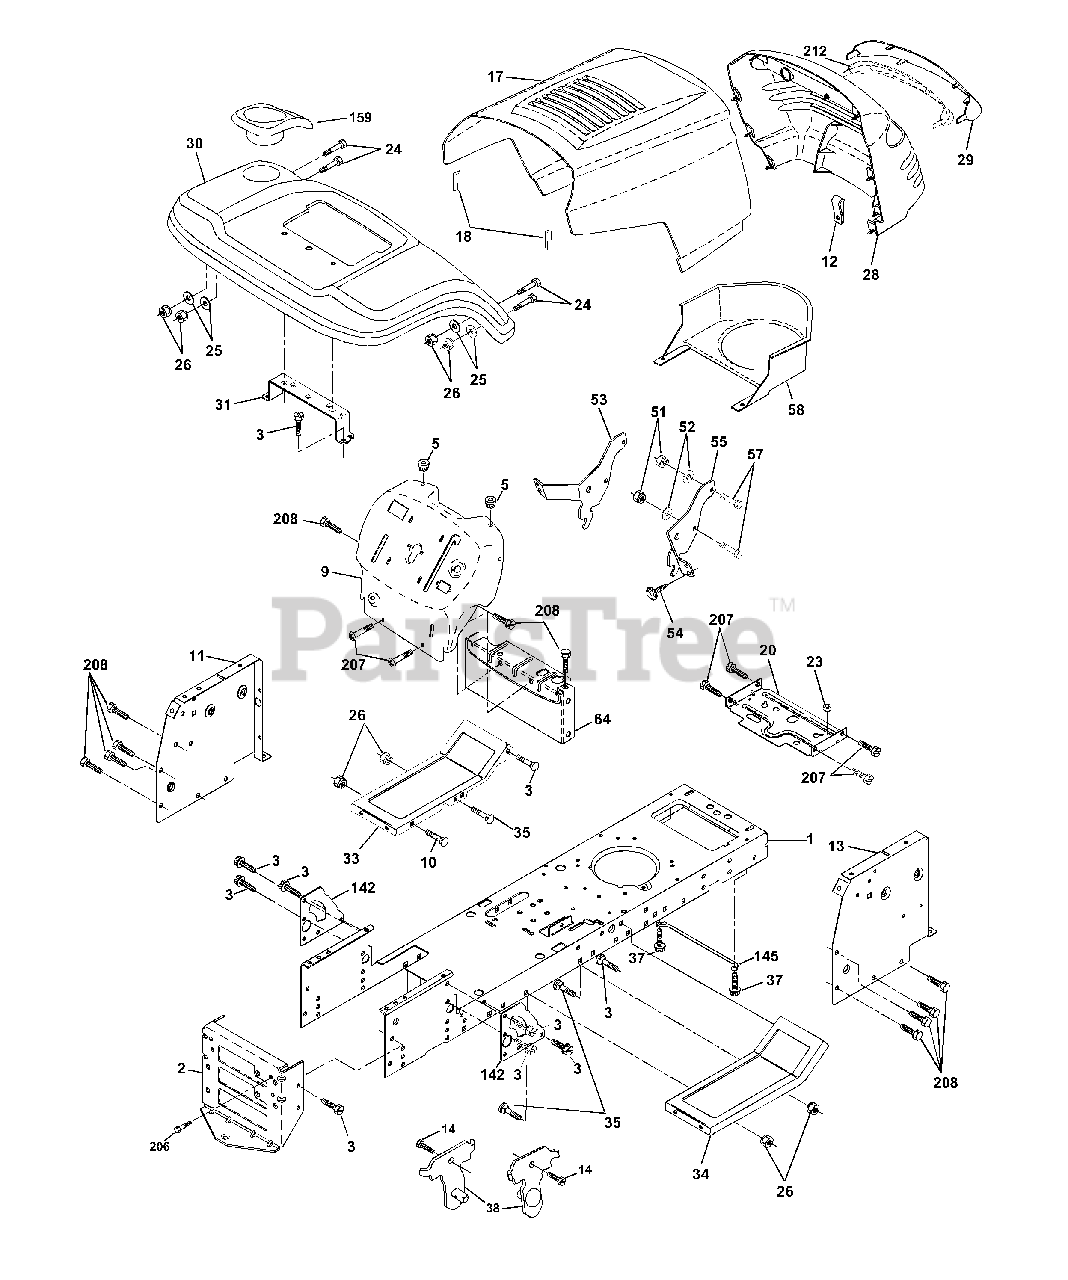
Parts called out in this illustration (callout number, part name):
1	Chassis
2	Drawbar
3	Screw 3/8-16 X .75
5	Bumper Hood/Dash
9	Dash P/L
10	Bolt Carriage 3/8-16 x 1
11	Panel Dash Lh
12	Clip Tinnerman
13	Panel Dash Rh
14	Screw Thdrol 3/8-16 x1/2
17	Hood LT/PL
18	Bumper Hood
20	Plate Mtg Battery Fuel Tank Fr
23	Bushing
24	Bolt Fin Hex 3/8-16 x 1 Gr 5
25	Washer 13/32 X 13/16 X 12 Ga
26	Nut Lock Hex W/Ins 3/8-16 Unc
28	Grille/Lens Asm
29	Lens LT/PL
30	Fender Footrest STLT Pnt
31	Bracket Fender
33	Footrest Pnt Lh
34	Footrest Pnt Rh
35	Bolt Rdhd Sht Sqnk 3/8-16 x 3/4
37	Screw Thdrol 6/16-18 x 1/2 TYT
38	Bracket Asm Pivot Mower Rear
51	Nut Lock Hex W/Ins 1/4-20
52	Washer 9/32 x 7/8 x 16 Ga.
53	Bracjet Grukke Lh
54	Screw Hex Wshd 8-18 x 7/8
55	Bracket Grille Rh
57	Bolt Hex 1/4-20 x 3/4
58	Duct Air
64	Dash Lower STLT
142	Plate Reinforcement STLT
145	Rod Pivot Chassis/Hood
159	Cupholder
206	Bolt Shoulder 5/16-18
207	Screw Thdrol 5/16-18 x 1/2
208	Screw Thdrol 3/8-16 x 1/2
212	Insert Lens Relect
